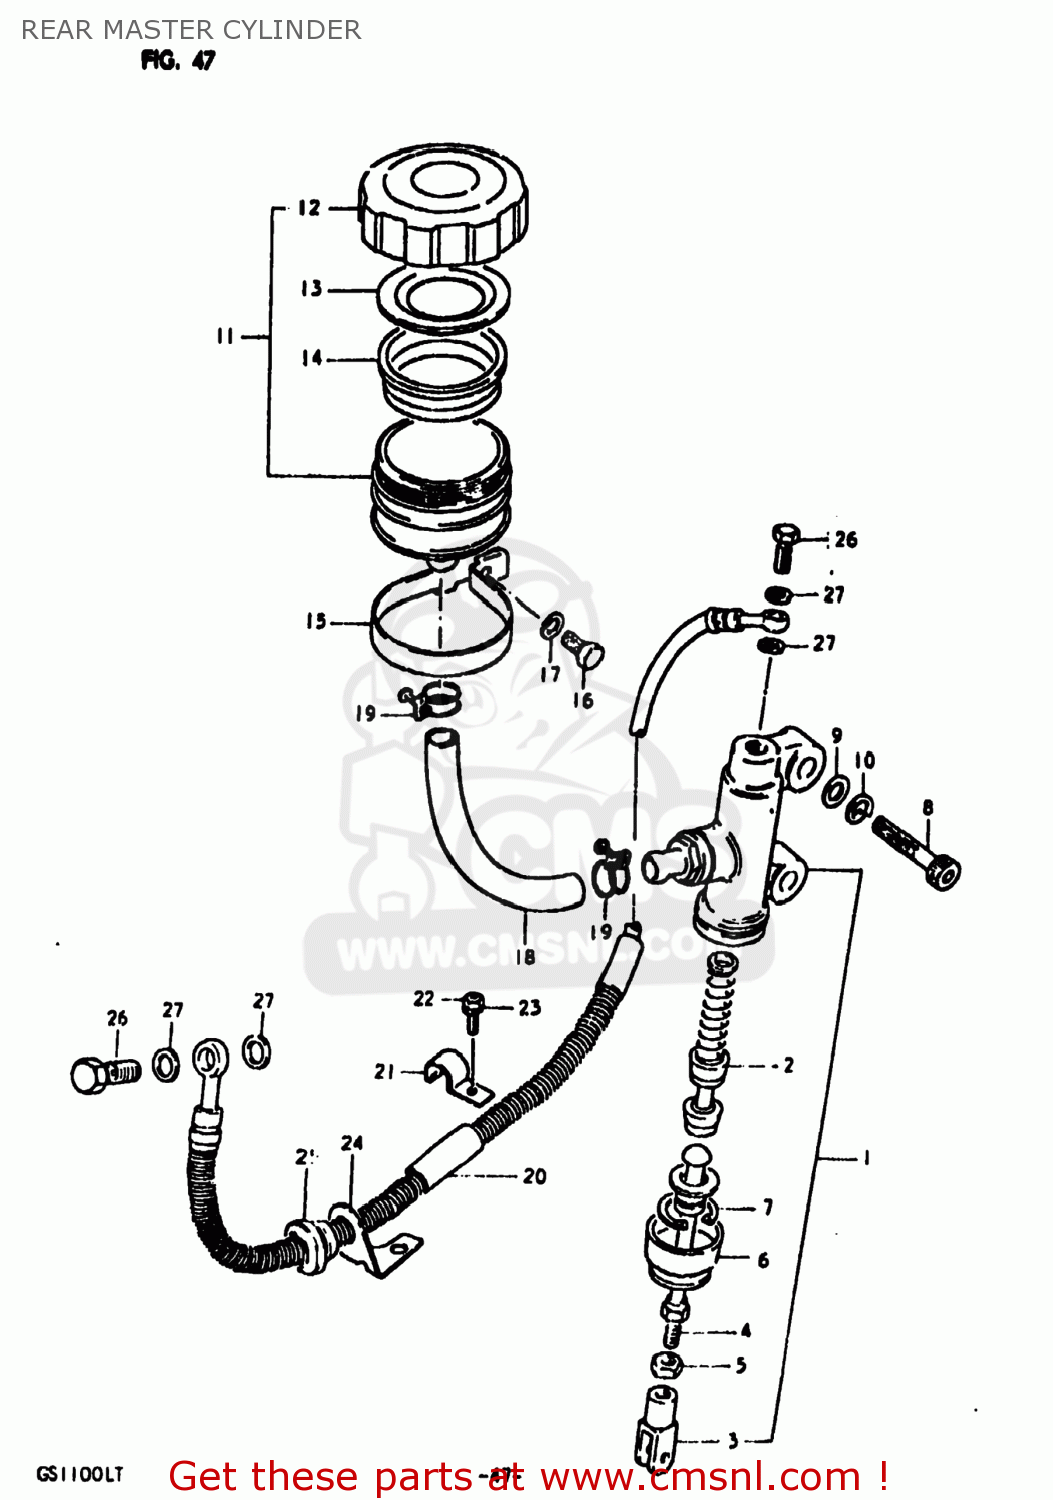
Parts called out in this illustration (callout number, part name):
1	CYLINDER ASSEMBLY,REAR MASTER
2	PISTON/CUP SET
3	YOKE
4	ROD,PUSH
5	NUT
6	BOOT
7	CIRCLIP
8	BOLT (8X30)
9	WASHER
10	LOCK WASHER
11	TANK ASSEMBLY,RESERVOIR
12	CAP
13	PLATE,DIAPHRAGM
14	DIAPHRAGM
15	CLAMP
16	BOLT, UPPER
17	LOCK WASHER
18	HOSE,RESERVOIR TANK
19	CLAMP
20	HOSE,REAR BRAKE
21	CLAMP,REAR BRAKE HOSE
22	SCREW(6X8)
23	LOCK WASHER
24	GUIDE,BRAKE HOSE
25	GROMMET,BRAKE HOSE GUIDE
26	BOLT,UNION
27	WASHER
